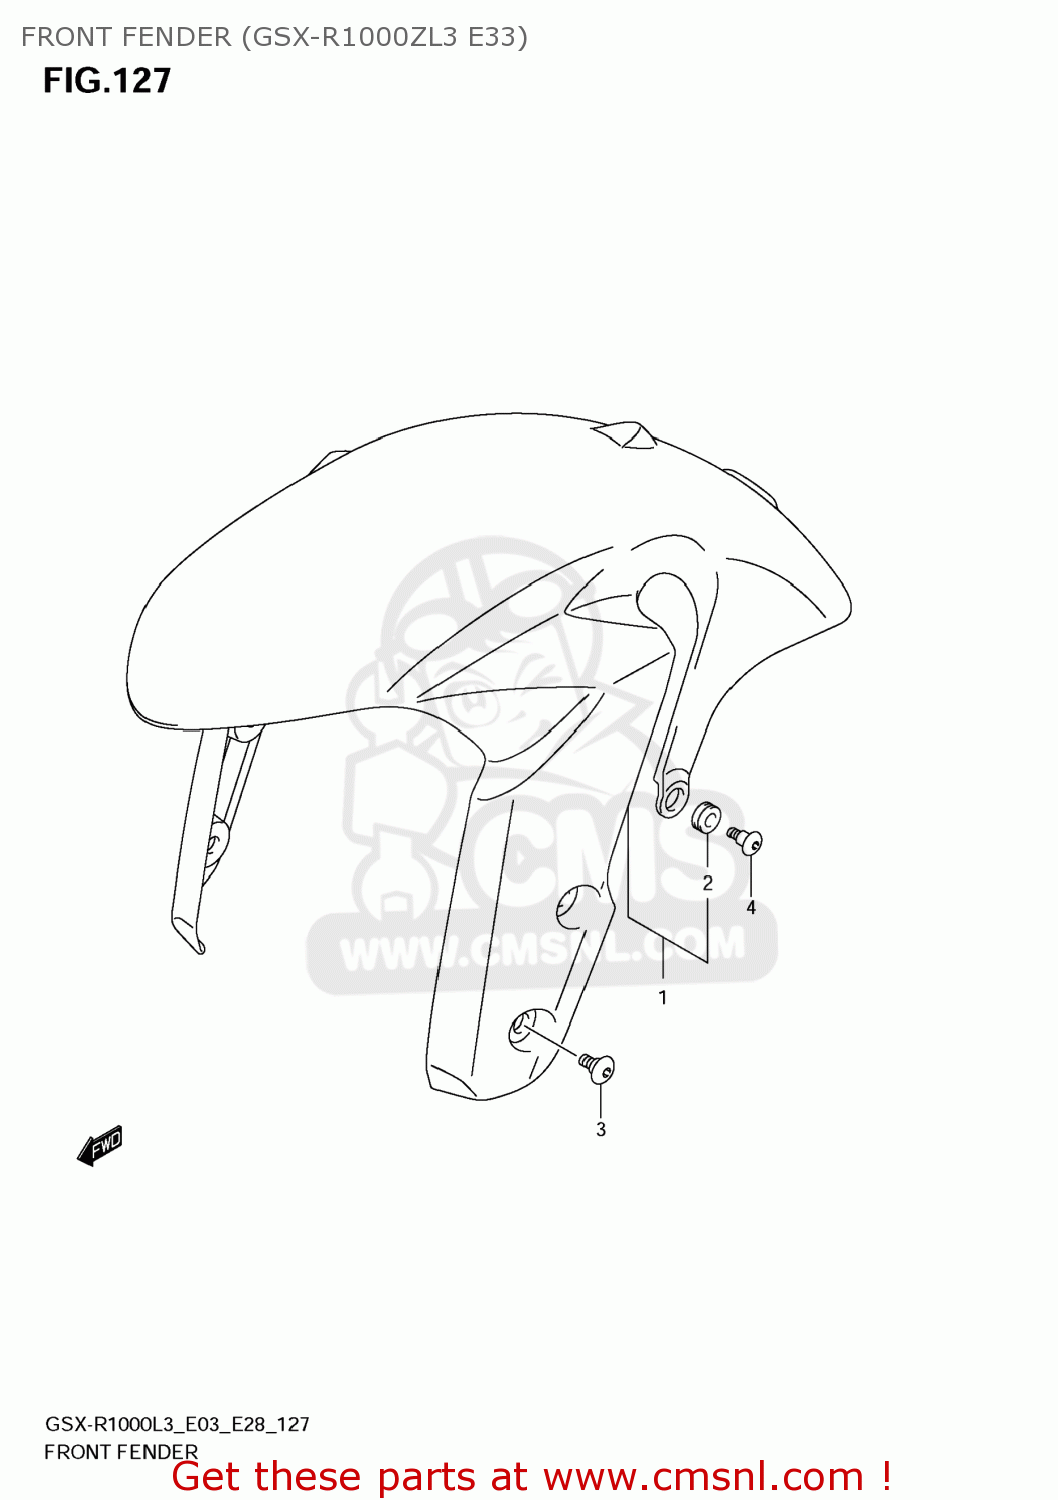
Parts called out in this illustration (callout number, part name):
1	FENDER ASSY,FR(WHITE)
2	CUSHION
3	SCREW(6X16)
4	SCREW(6X16)
